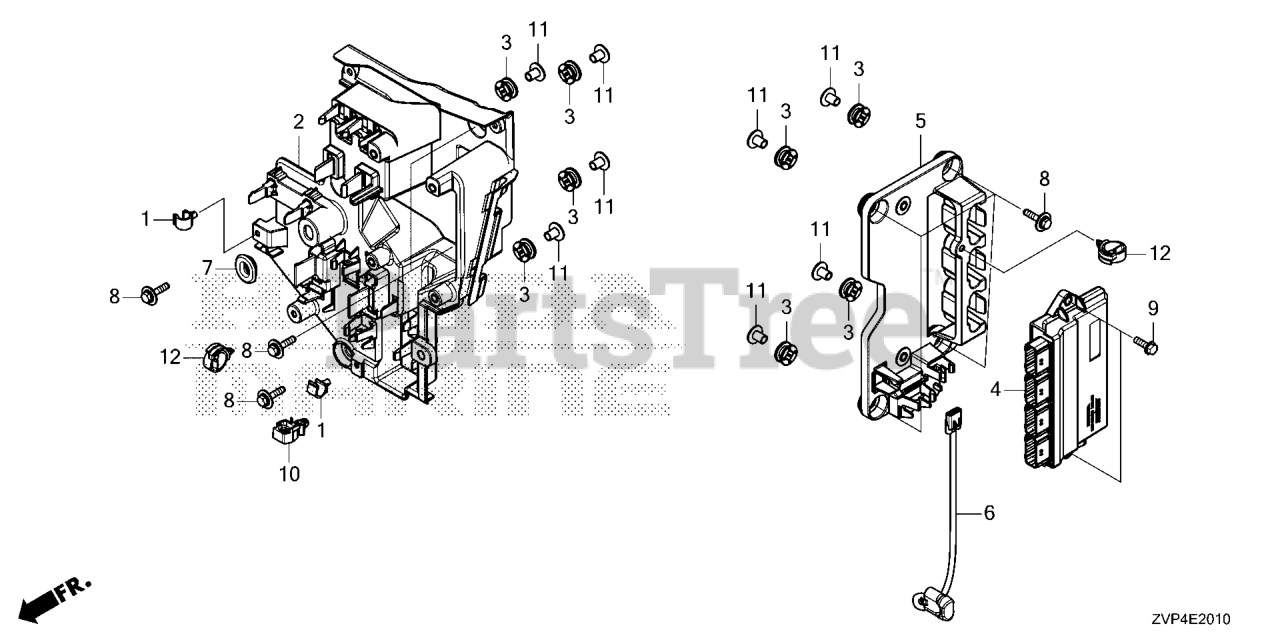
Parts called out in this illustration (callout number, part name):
1	CLAMP B, FUEL TUBE
2	CASE, ELEC PARTS
3	GROMMET, ELECTRONIC PARTS CASE
6	SWITCH ASSY., POWER TILT
7	GROMMET, AIR CLEANER HOUSING
8	BOLT-WASHER (6X27)
9	BOLT, FLANGE (6X20)
11	COLLAR (12X6.5)
12	CLIP, WIRE HARNESS *NH1L* (BLACK)
